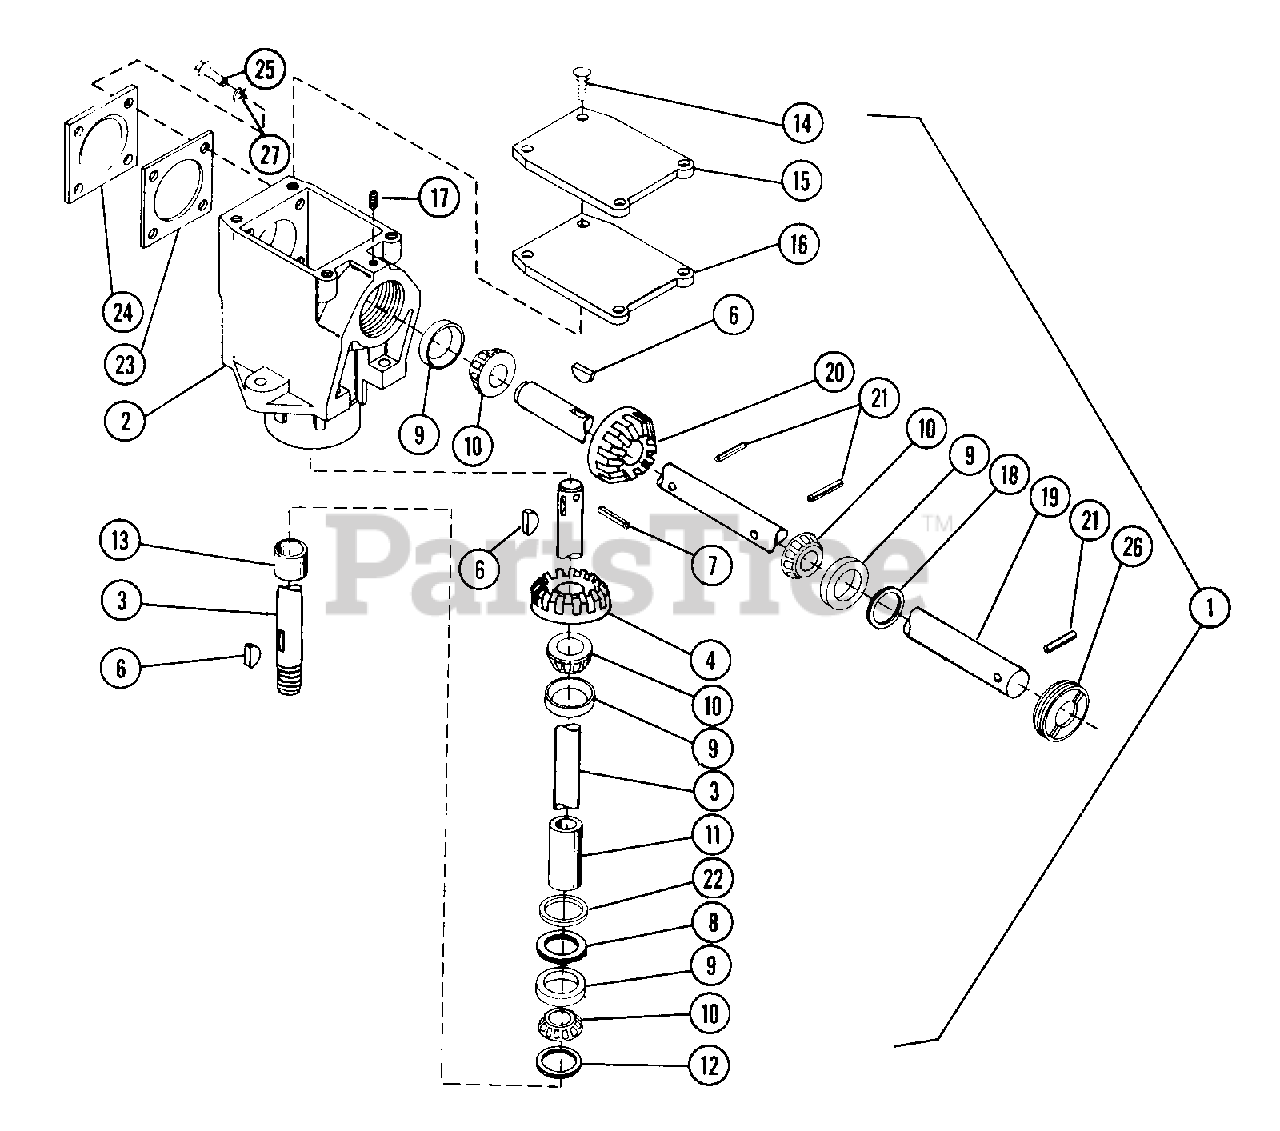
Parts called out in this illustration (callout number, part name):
1	MOWER GEAR CASE 48 IN
2	GEAR CASE
3	OUTPUT SHAFT
4	GEAR - BEVEL
6	KEY-WDRF .25X.750X.313 SAE91
7	@PIN-GRV .188X1.25 TP E ALLOY
8	LOAD RING KIT
9	BRG-CUP 1.781X.475
10	BRG-CONE .750X.61
11	BEARING SPACER
12	SEAL 1.000X1.980X.375
13	SPACER
14	SCR-TAP 8-32X.50 HWH PL TR
15	COVER, GEAR CASE
16	TOP GASKET
17	SCR-SET .25-20X.25 SKHCUPNY OH
18	SEAL .750X1.499X.225
19	SHAFT, INPUT
20	GEAR - BEVEL
21	PIN-ROLL .188X1.00
22	WSHR-FL-STL 1.406X1.750X.059PL
23	SIDE COVER GASKET
24	BEARING SIDE COVER
25	BLT-HEX .31-18X.50 PL GR2
26	ADJUSTMENT PLUG
27	WSHR-LK .312X.097 PL HVY
